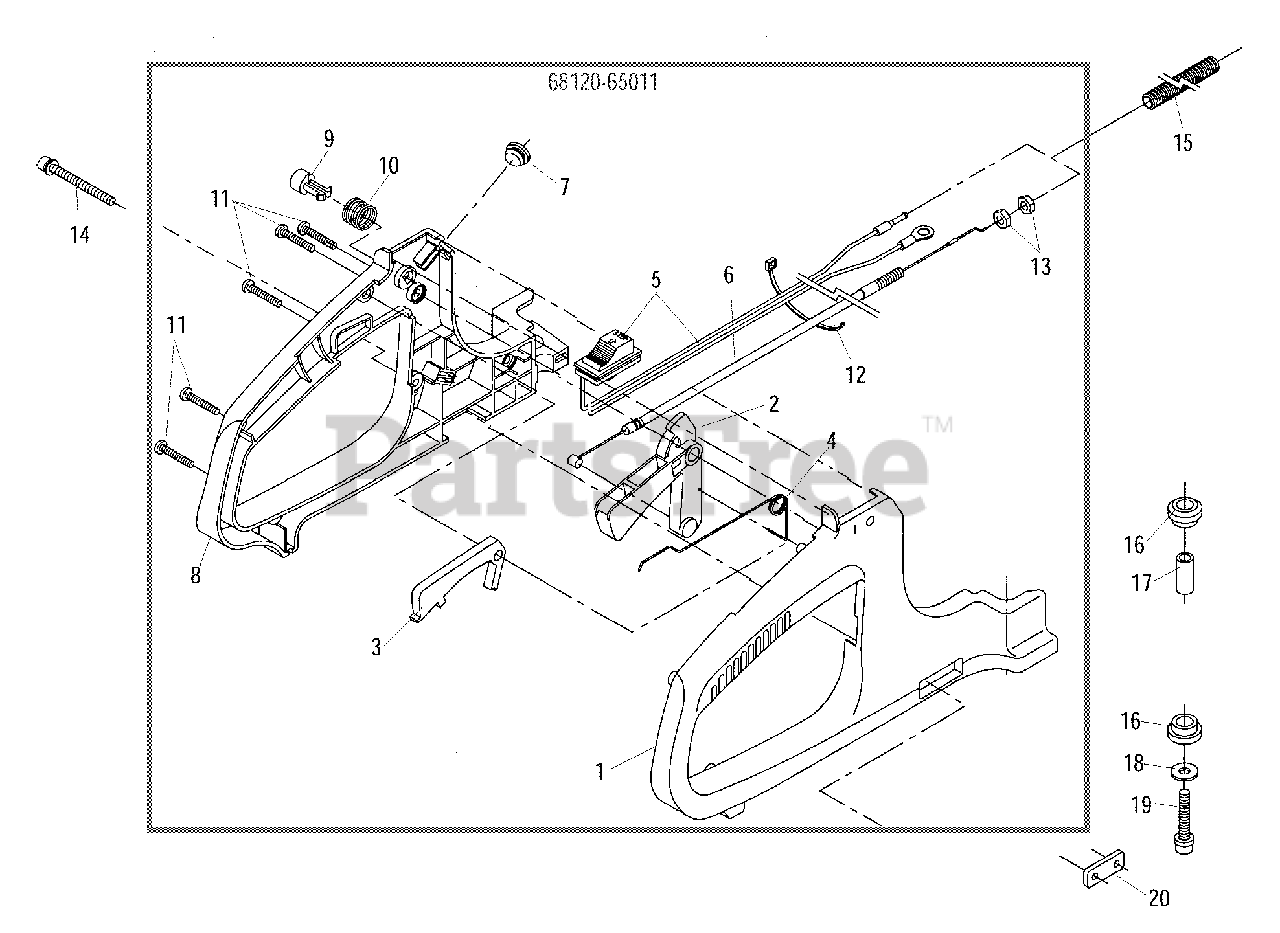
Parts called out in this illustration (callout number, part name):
1	HANDLE - RIGHT
2	TRIGGER, THROTTLE
3	LEVER, TRIGGER LOCKOUT
4	SPRING, TRIGGER
5	SWITCH, IGNITION
6	CABLE, THROTTLE
7	PLUG
8	HANDLE - LEFT
9	BUTTON, THROTTLE LOCK
10	SPRING
11	SCREW - 4X8 -- TAPPING
12	TIE, CABLE
13	NUT - 6
14	SCREW - 5X45
15	TUBE, PROTECTIVE - CORRUGATED
16	CUSHION
17	COLLAR - 6
18	WASHER - 16
19	SCREW - 6X35
68120-65011	HANDLE ASSY - REAR
